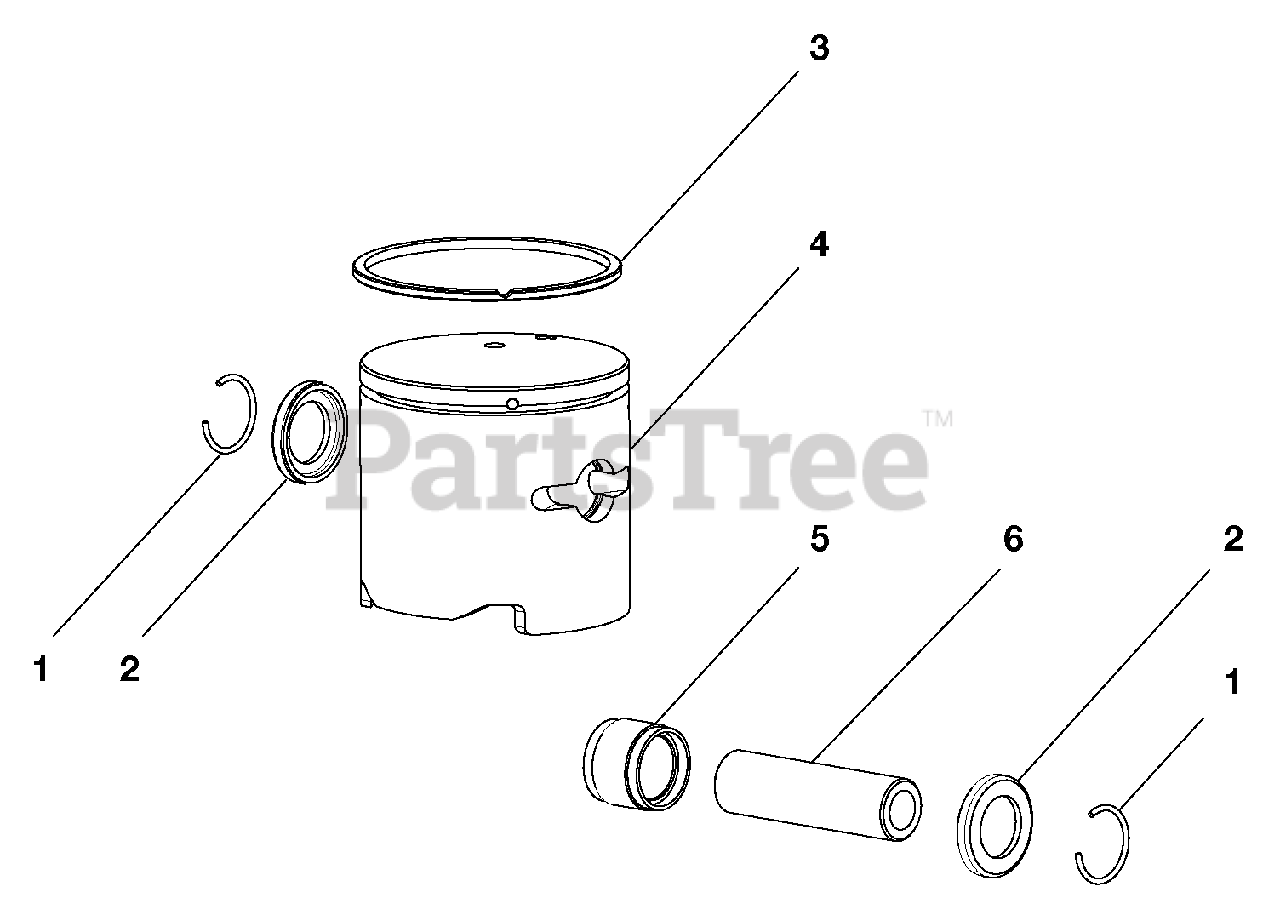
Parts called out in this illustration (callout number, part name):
1	WRIST PIN CLIP RING
2	WASHER
3	PISTON RING
5	NEEDLE BEARING (ID 8 X 8.8)
6	WRIST PIN
